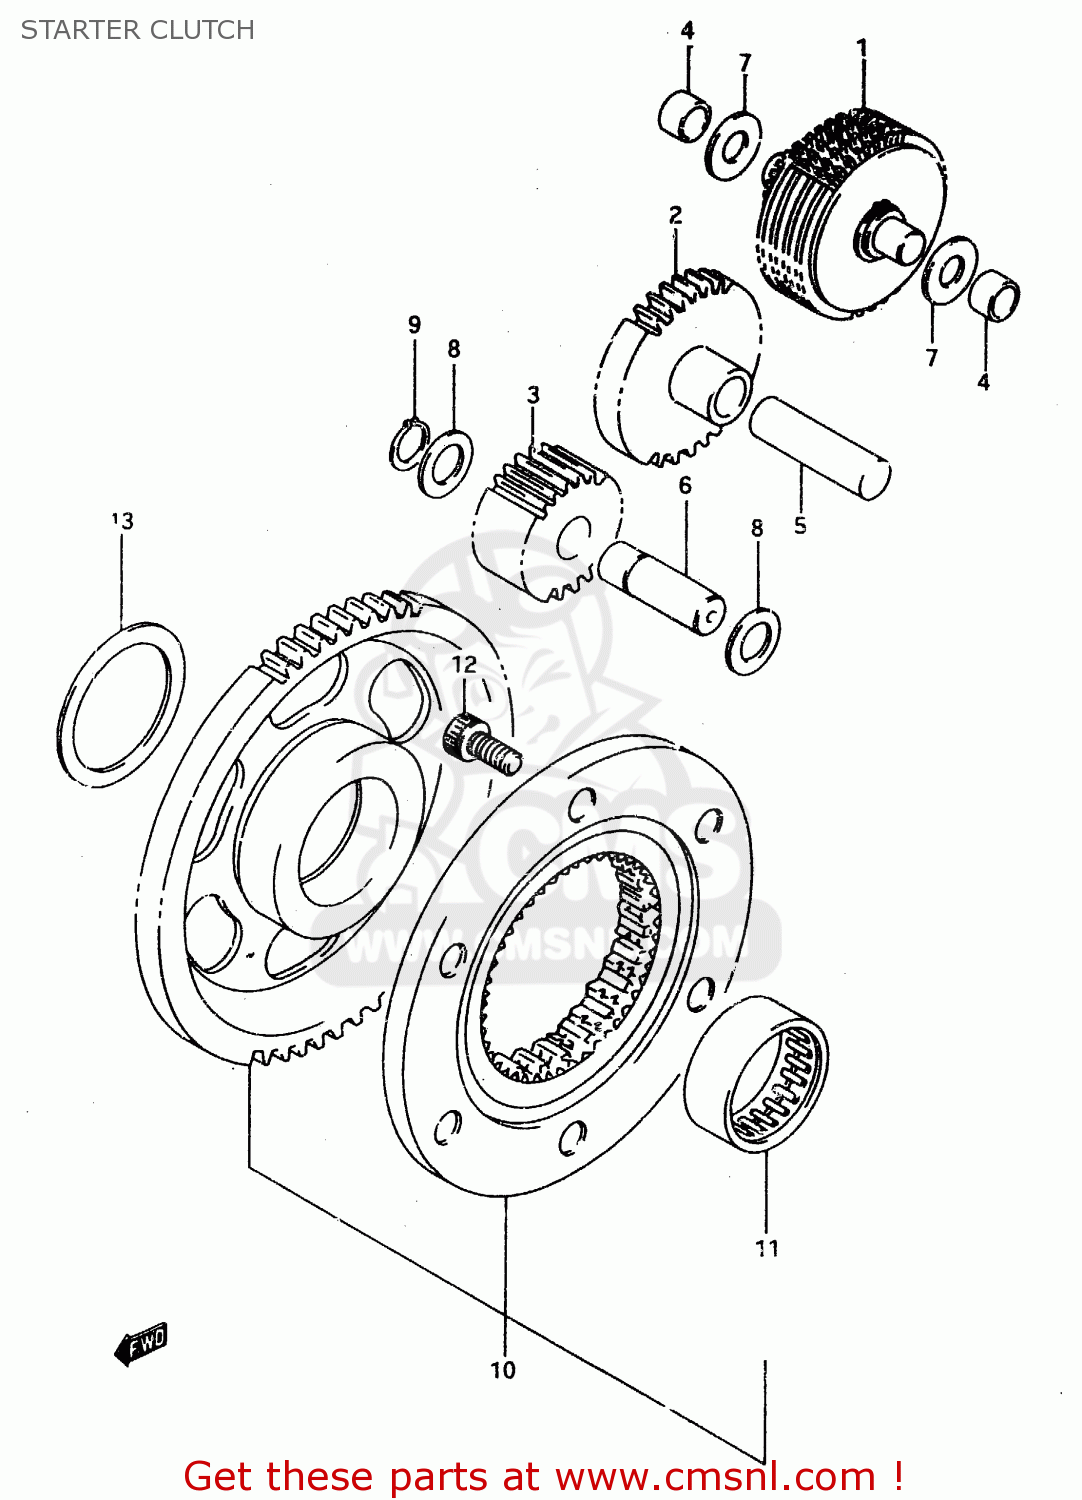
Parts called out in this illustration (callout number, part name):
1	LIMITER ASSEMBLY,STARTER IDLER GEAR
2	GEAR,STARTER IDLE NO.2(NT:27)
3	GEAR,STARTER IDLE NO.3
4	BUSH,LIMITER GEAR SHAFT
5	PIN
6	SHAFT,STARTER IDLE GEAR
7	WASHER
8	SHIM
9	CIRCLIP,12 MM
10	CLUTCH SET,STARTER
11	BEARING(31X39X17.8)
12	BOLT
13	SHIM
